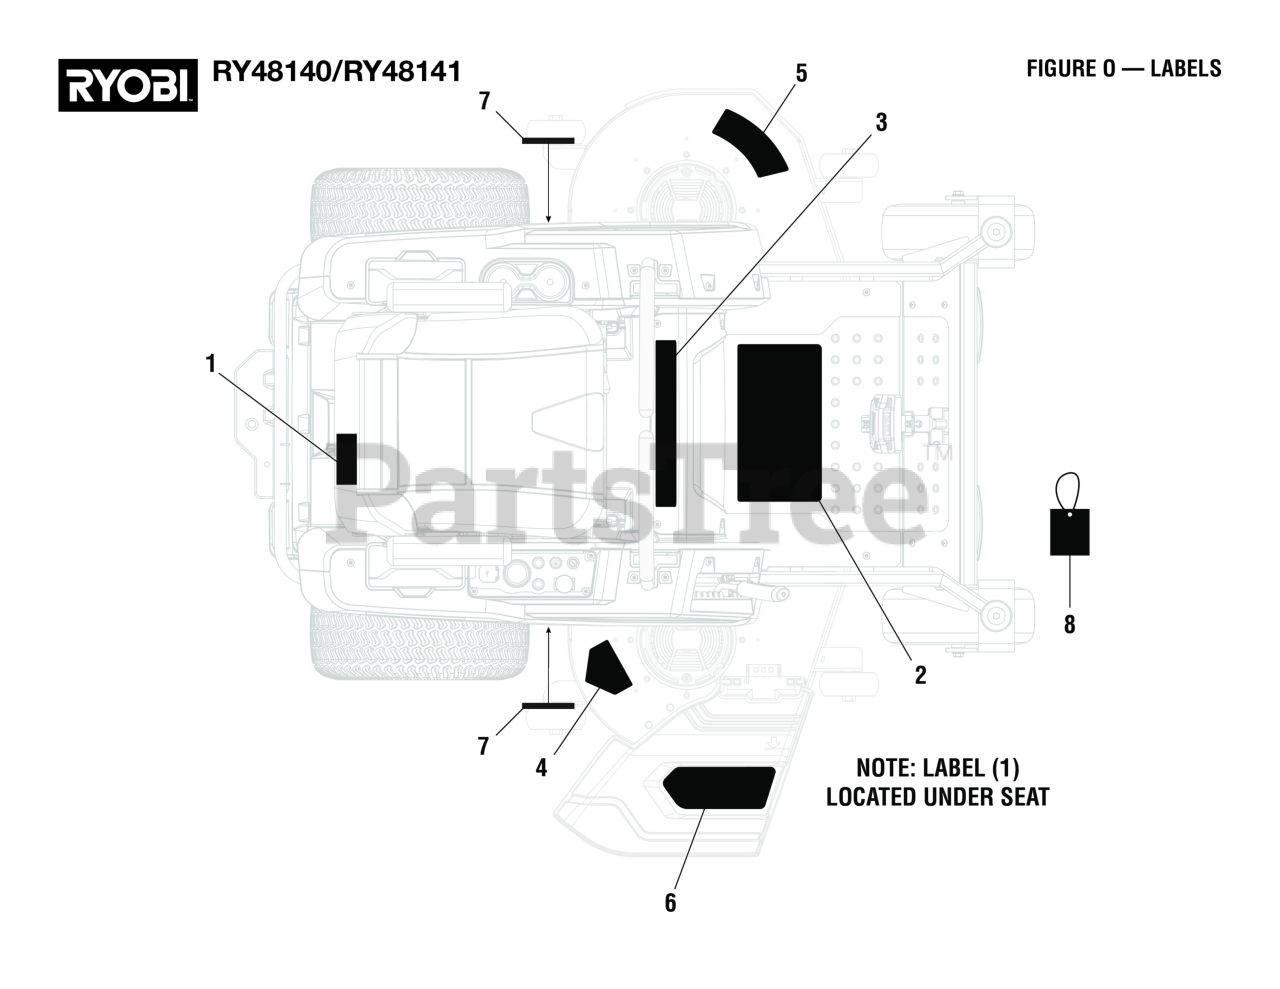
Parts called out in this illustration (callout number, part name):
1	Data Label
2	FLOOR DANGER LABEL, ENGLISH
2	FLOOR DANGER LABEL, SPANISH
3	INSTRUCTION LABEL, ENGLISH
3	INSTRUCTION LABEL, SPANISH
4	No Hands CPSC Danger Label, English
4	No Hands CPSC Danger Label, Spanish
5	Deck Danger Label, English
5	Deck Danger Label, Spanish
6	Discharge Danger Label, English
6	Discharge Danger Label, Spanish
7	Pinch Point Icon Label
8	Prop 65 Hangtag
